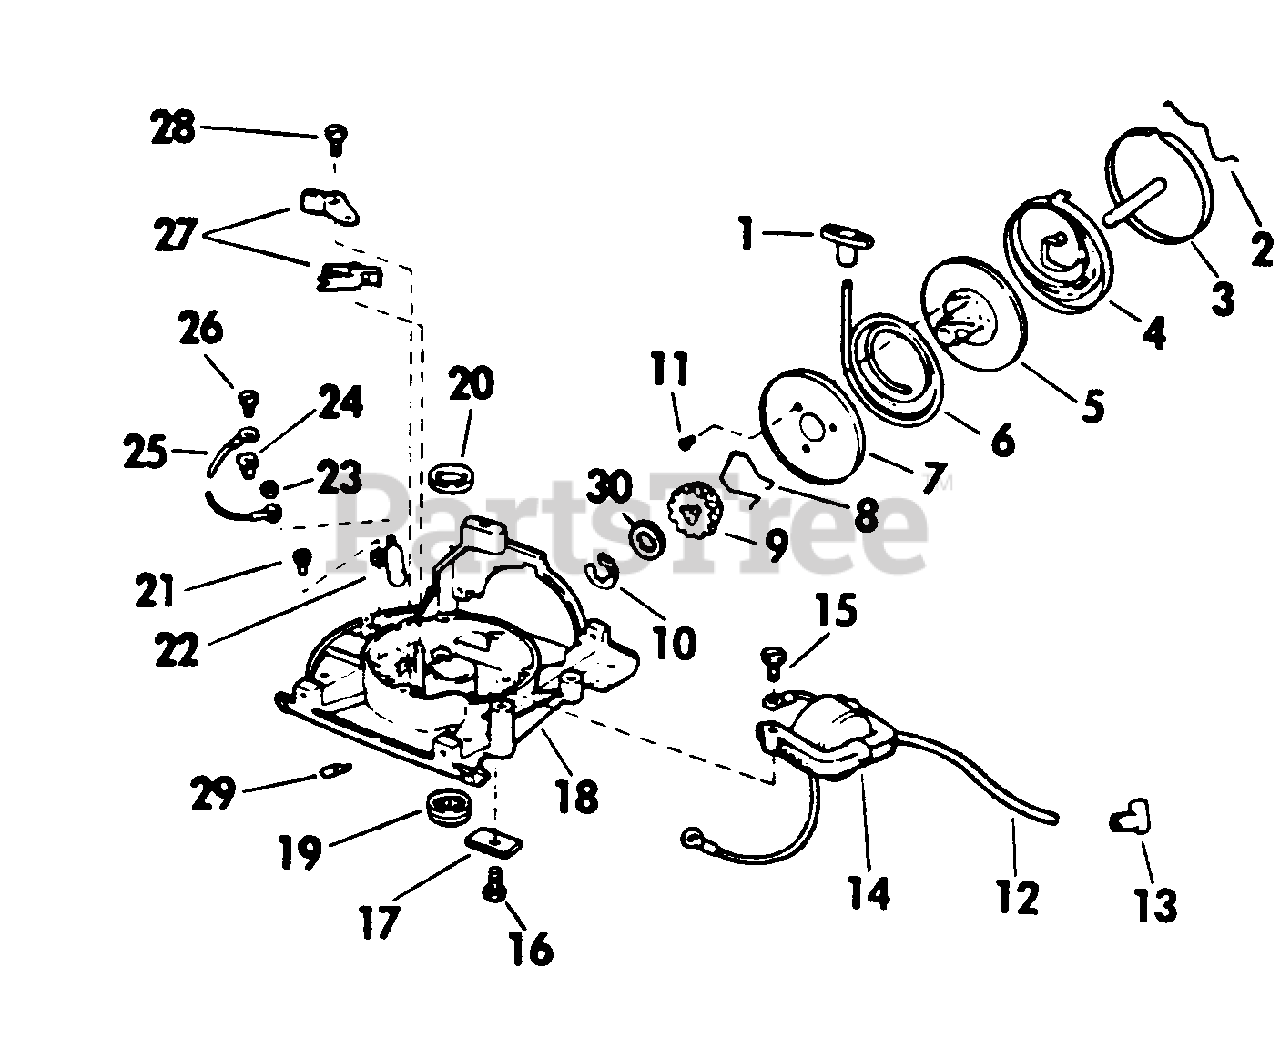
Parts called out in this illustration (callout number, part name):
1	Handle-Starter
2	Spring-Starter Rope Retainer
3	Spring-Cup-Pin Assy.
4	Spring-Starter
5	Pulley-Starter
6	Rope-Starter
7	Plate-Starter Pulley
8	Spring-Starter Pinion
9	Pinion-Starter
10	Retainer-Push-On
11	Screw-Threaded Cutting Starter
12	High Tension Lead Assy.
13	Cover and Terminal Assy.
14	Coil & Lamination Assy.
15	Screw-Lamination Mtg.
16	Screw-Starter Attach.
17	Clamp-Starter Pin
18	Arm. Pl. Brg. & Oil Seal Assy.
19	Bearing
20	Oil Seal
21	Screw-Cond. Mtg.
22	Cond. & Nut Assy.
24	Grommet-Nylon
25	Terminal & Lead Assy.
26	Screw-Shut-Off Sw.
27	Brkr. Base & Arm Assy.
28	Screw-Breaker Base
